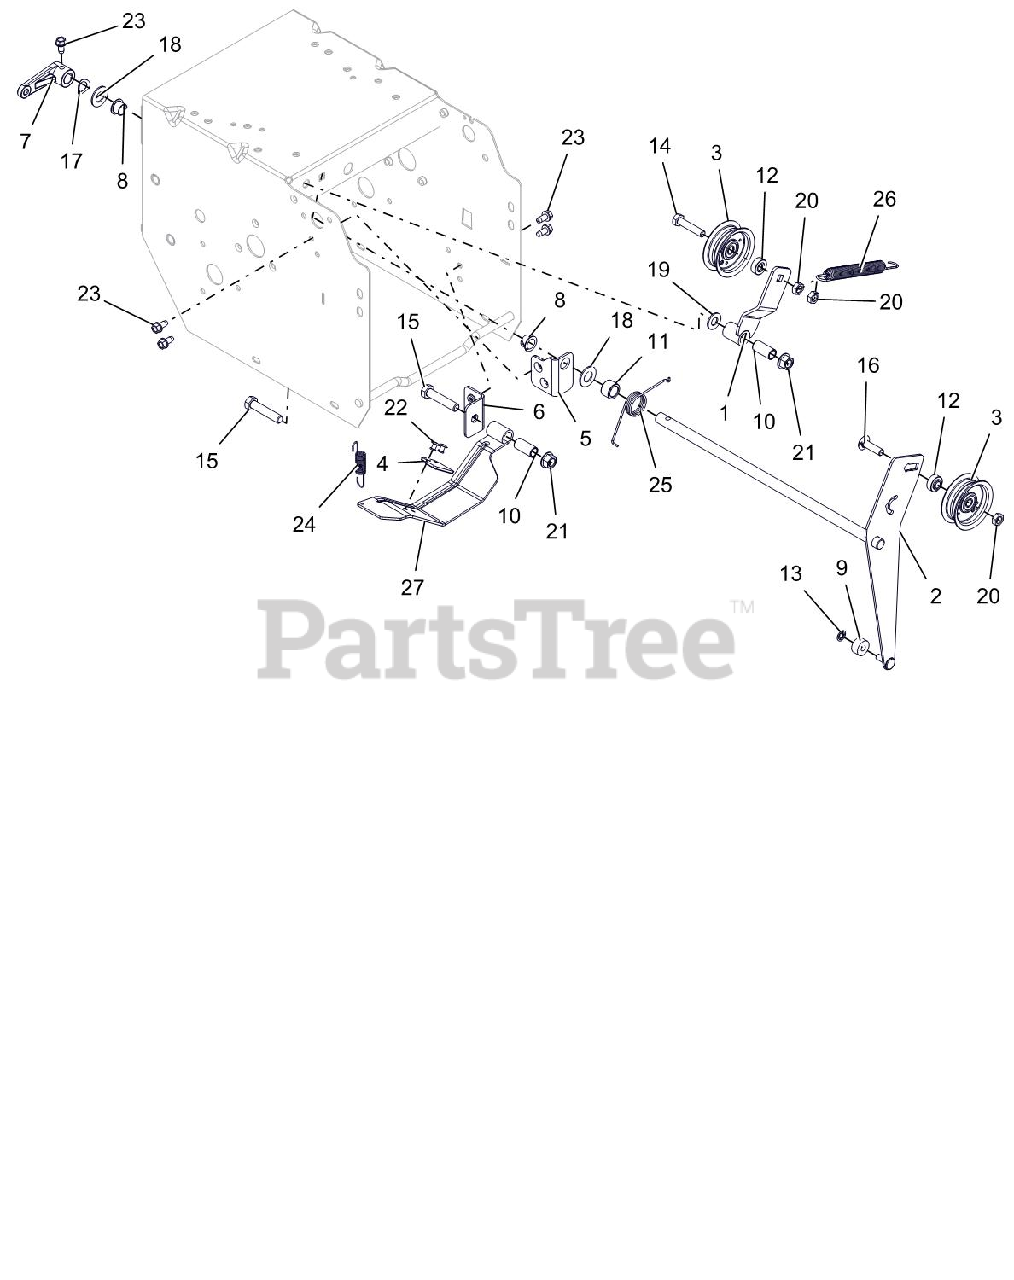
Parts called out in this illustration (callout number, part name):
1	ARM, TRACTION IDLER
2	WELDMENT, ATTACHMENT IDLER ARM
3	IDLER, FLAT - 2.00"
4	PAD, BRAKE
5	BRACKET, MOUNT - IDLER ARM
6	BRACKET, MOUNT - BRAKE
7	ARM, CLUTCH - ATTACHMENT
8	BUSHING, POLYLINER-.50 SPLIT
9	BSHG,SLV .265 X .625 X .375
10	BSHG-SLV .385X.500X1.045
11	BSHG-SLV .510X.751X.475
12	SPCR, BRG .315X.500X.358X.281
13	RG-RTNG-EXT .250X.010
14	@BLT-HEX .31-18X1.50 GR5 YWZC
15	@BLT-HEX .38-16X1.75 GR5 YWZC
16	BLT-RDHDSQSHNK.31-18X1.13 G5YZ
17	WSHR-WAVE .50X.75X.015 .13FRHT
18	WSHR-FL-STL.531X1.00X.063 YWZC
19	@WSHR-FL-STL.406X.812X.065 YWZ
20	@NUT-LK-CTR-JAM .31-18 YWZC
21	@NUT-LK-TOP-FLG .38-16 YWZC
22	RVT-POP .187 YZ
23	SCR-TAP .25-20X.50 HWH TR YWZ
24	SPRING-EXT .437 X .438 X 2.64
25	SG-TORS .075 X .955
26	SPRING, SWIVEL HOOK EXTENSION
27	BRAKE ARM W/PAD
